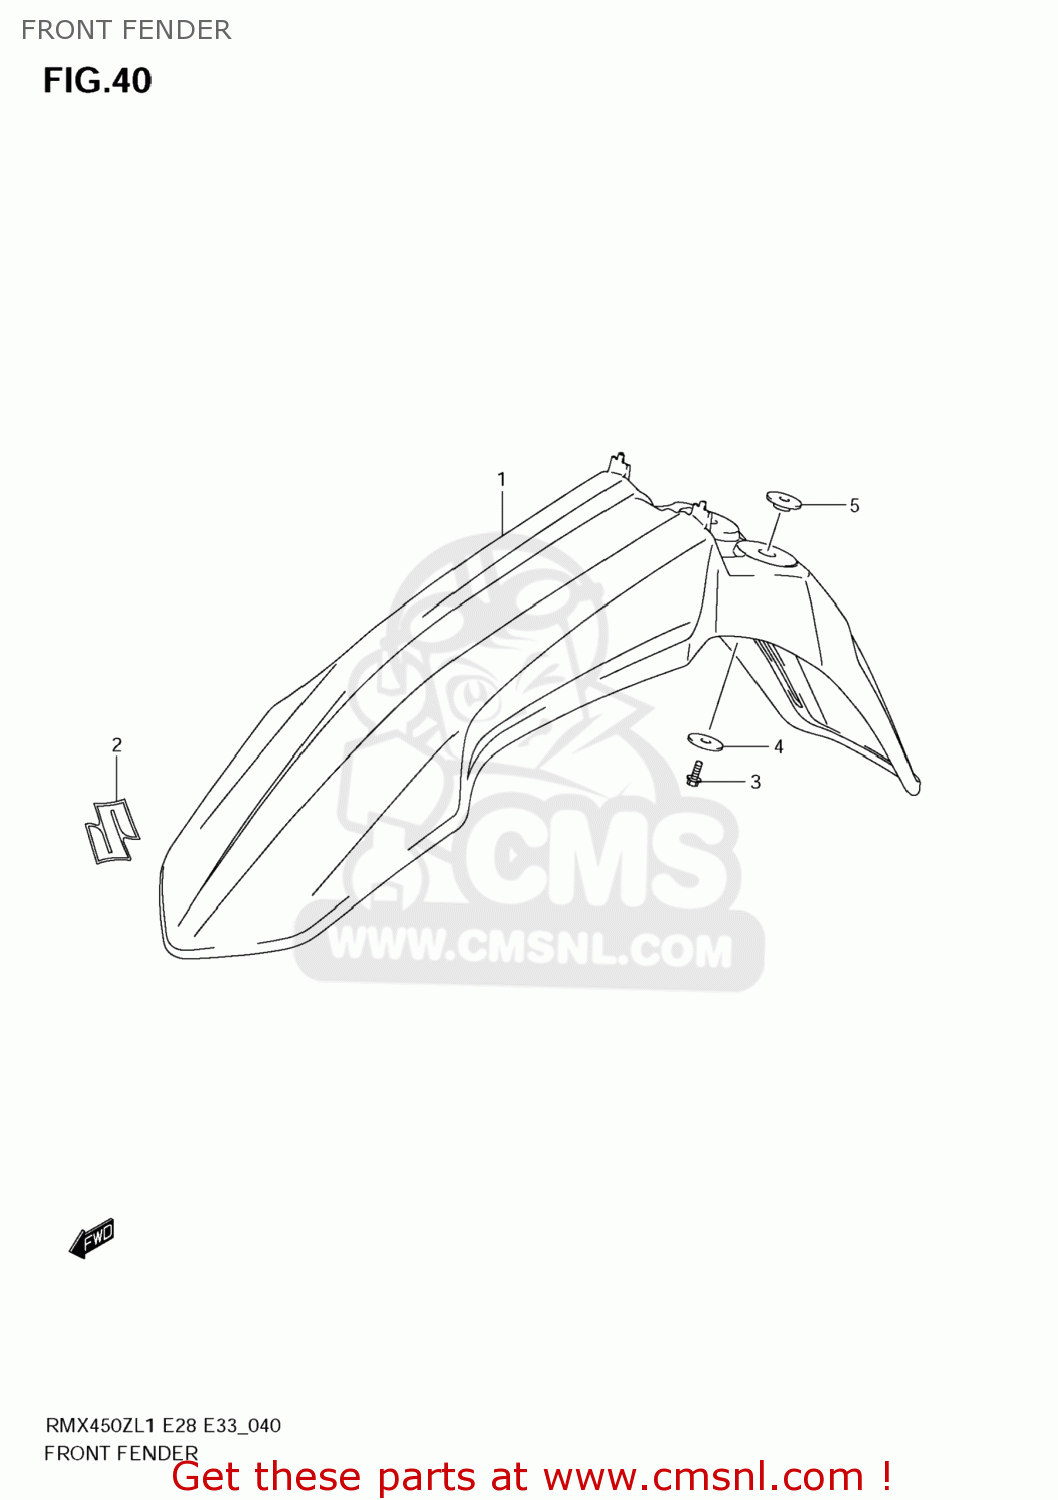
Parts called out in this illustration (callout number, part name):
1	FENDER,FR
2	EMBLEM,S
3	BOLT
4	WASHER,FUEL TANK FR
5	WASHER
